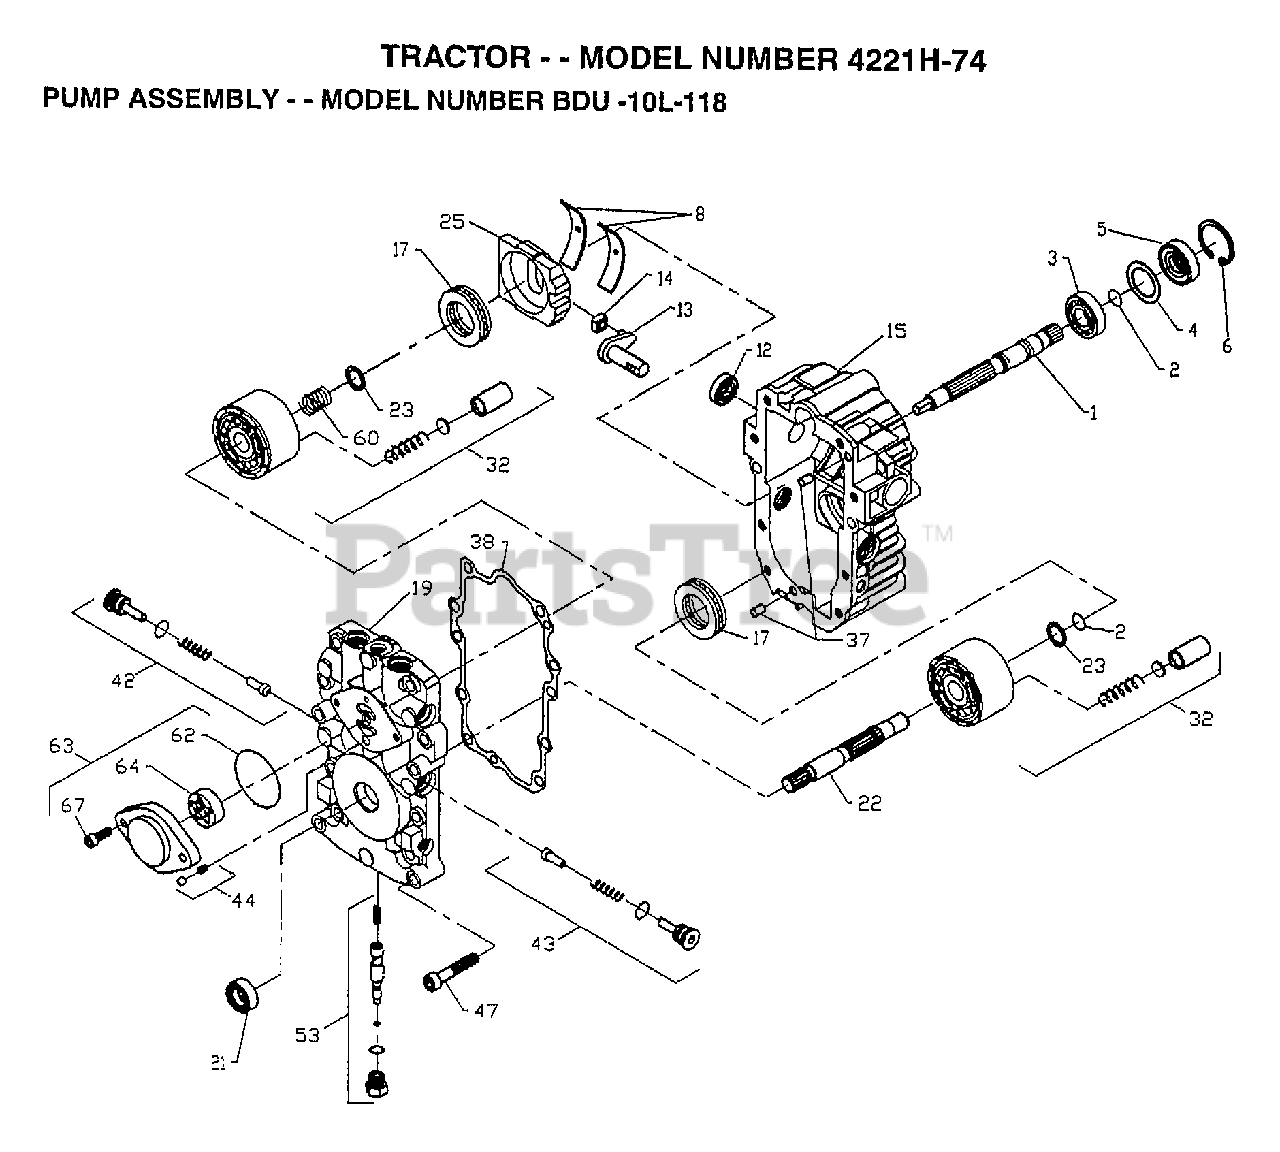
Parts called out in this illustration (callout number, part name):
1	SHAFT.PUMP.50158
2	RETAINIANG RING-(2003016)
3	BALL BEARING
4	SPACER
5	SEAL LIP
6	RING.RET.2003052
8	CRADLE BEARING (2003023)
12	SEAL.9008000-0126
13	TRUNION ARM (2003005)
14	GUIDE.2000015.HYD
15	KIT.HSG.2513035.
19	KIT.CENT.2513006
21	LIP SEAL-9008000-0127
22	SHAFT.MOT.2003034
23	WASHER.2003017
25	"SWASHPLATE,VARIAB"
32	BLOCK.CLYN.70079.
37	PIN
38	GASKET.20030600
42	KIT.VALVE.2510050
43	KIT.VALVE.2510050
44	KIT.RELI.2510011.
47	SCREW9007314-0808
53	"KIT,BYPASS VALVE"
60	SPRING.2003014.
62	0RING.90041011340
63	KIT.CHARG.2513027
64	GEROTOR.J1041008
67	SCREW.CAP.50095.
